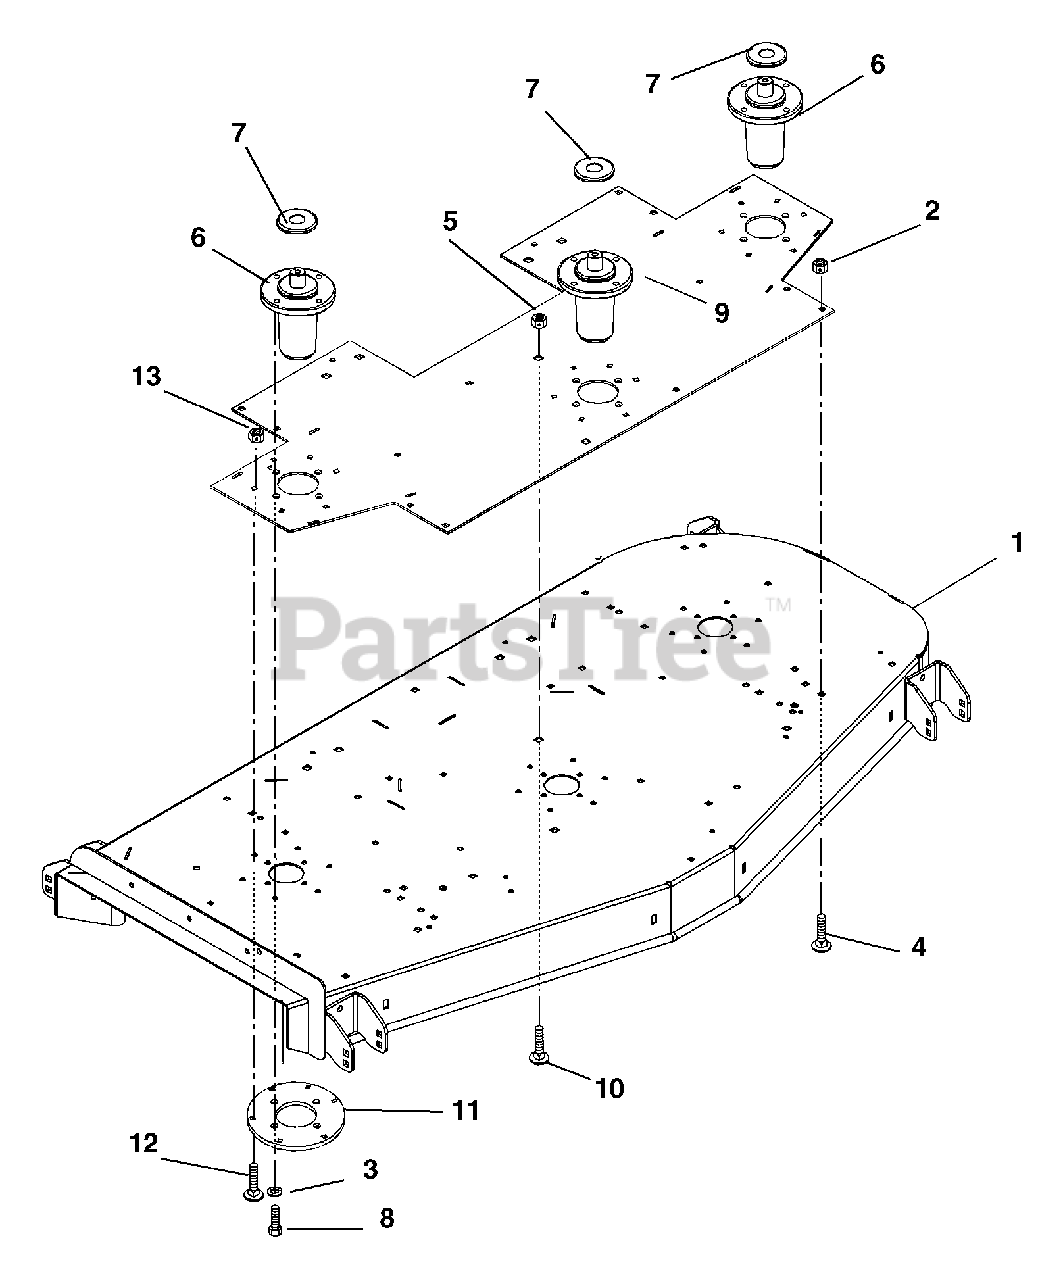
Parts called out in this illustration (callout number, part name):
1	Weldment, 72" Deck (Side Discharge)
2	Plate, 72" Reinforcment
3	Washer-Locking .38 x .094
4	Bolt-Round Head Square Neck .38-16 x 2.75 Grade 5
5	Nut-Locking-Nylon .38-16
6	Assembly, Spindle L-Hub
7	Slinger-Dust
8	Bolt-Hex .38-16 x 1.00 Grade 5
9	Assembly, Spindle
10	Bolt-Round Head Square Neck .38-16 x 1.00 Grade 2
11	Plate, Spindle Reinforcement
12	Bolt-Round Head Square Neck .38-16 x 1.00 Grade 5
13	Nut-Locking-Center .38-16
